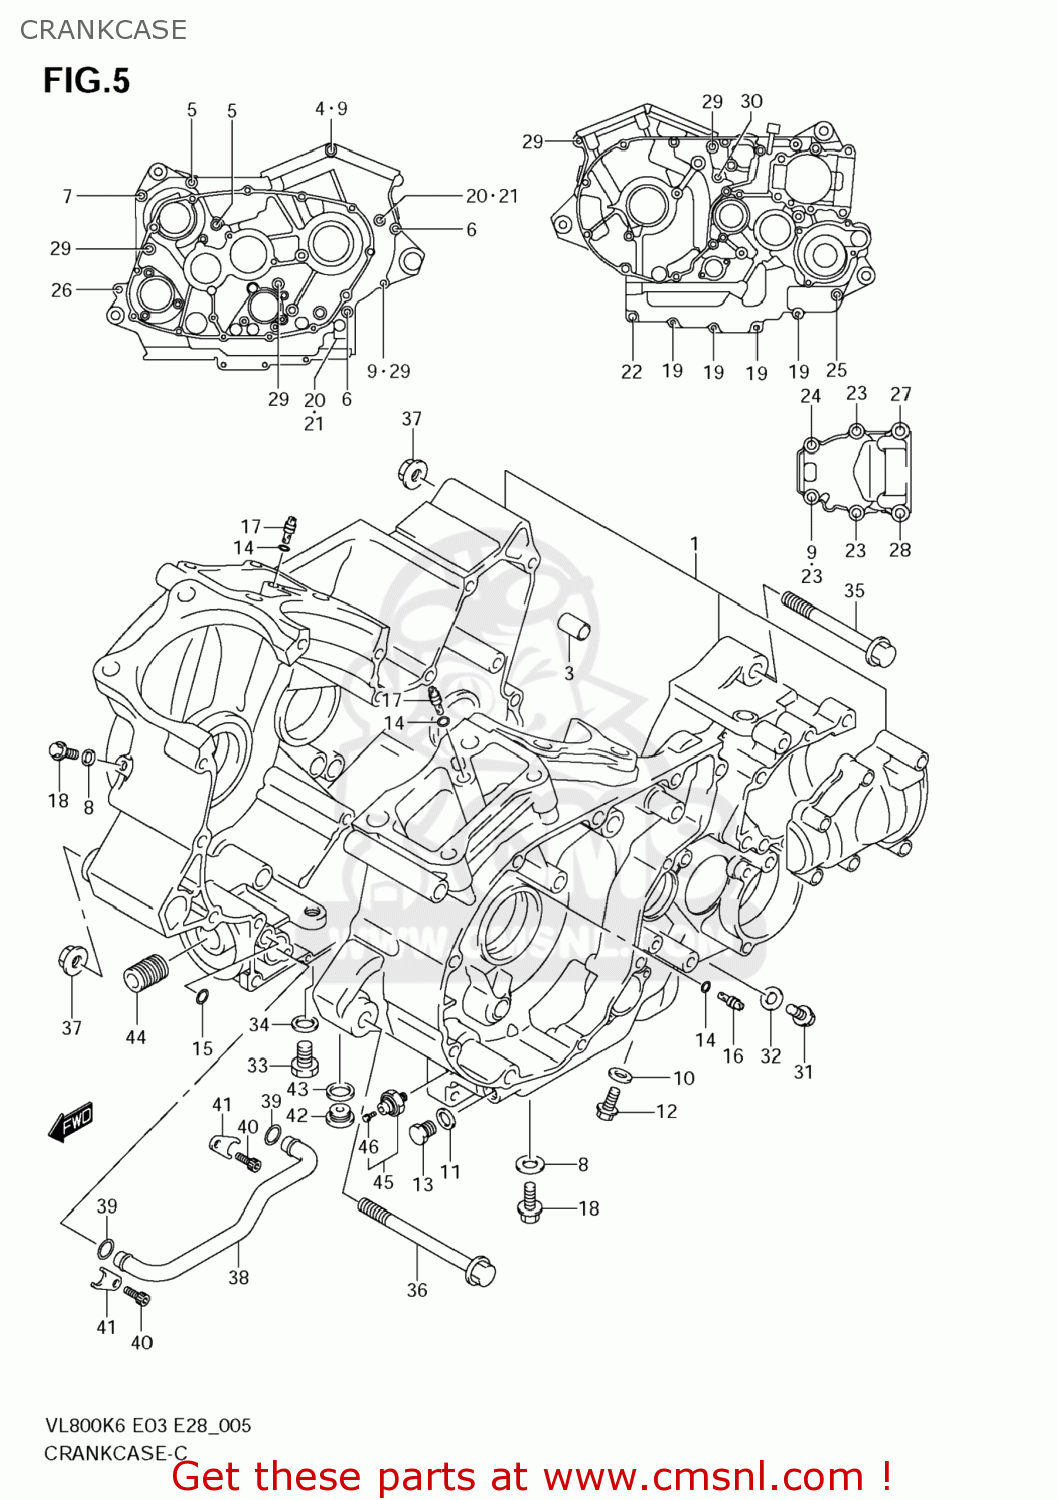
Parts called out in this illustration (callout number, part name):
1	CRANKCASE SET
2	WASHER(48.1X64X1.94)
3	PIN(8.4X11X20)
4	BOLT(8X160)
5	BOLT(8X120)
6	BOLT(8X105)
7	BOLT(8X95)
8	GASKET(5.8X13X1.2) (NAS)
9	GASKET(8.2X14X1) (NAS)
10	GASKET(10X14X3.6) (NAS)
11	GASKET(13.8X18.8X4.8) (NAS)
12	PLUG(10X12)
13	PLUG(14X12)
14	O RING(D:1.2,ID:4)
15	O RING(D:1.9,ID:12.6)
16	JET,OIL GALLERY
17	JET,AIR(14)
18	BOLT
19	BOLT
20	BOLT
21	GASKET(8.2X14X1) (NAS)
22	BOLT
23	BOLT
24	BOLT
25	BOLT
26	BOLT
27	BOLT
28	BOLT
29	BOLT(8X95)
30	BOLT
31	BOLT(8X12)
32	GASKET(8.2X14X1) (NAS)
33	PLUG(12X20)
34	GASKET(12.1X16.2X3.7) (NAS)
35	BOLT(10X135)
36	BOLT(10X160)
37	NUT
38	PIPE,OIL GALLERY
39	O RING(D:3.1,ID:14.8)
40	BOLT(6X12)
41	CLAMP,OIL PIPE
42	PLUG
43	GASKET(16X22X2) (NAS)
44	UNION,OIL STAND
45	SWITCH ASSY,OIL PRESSURE
46	BOLT,OIL PRESSURE SWITCH
